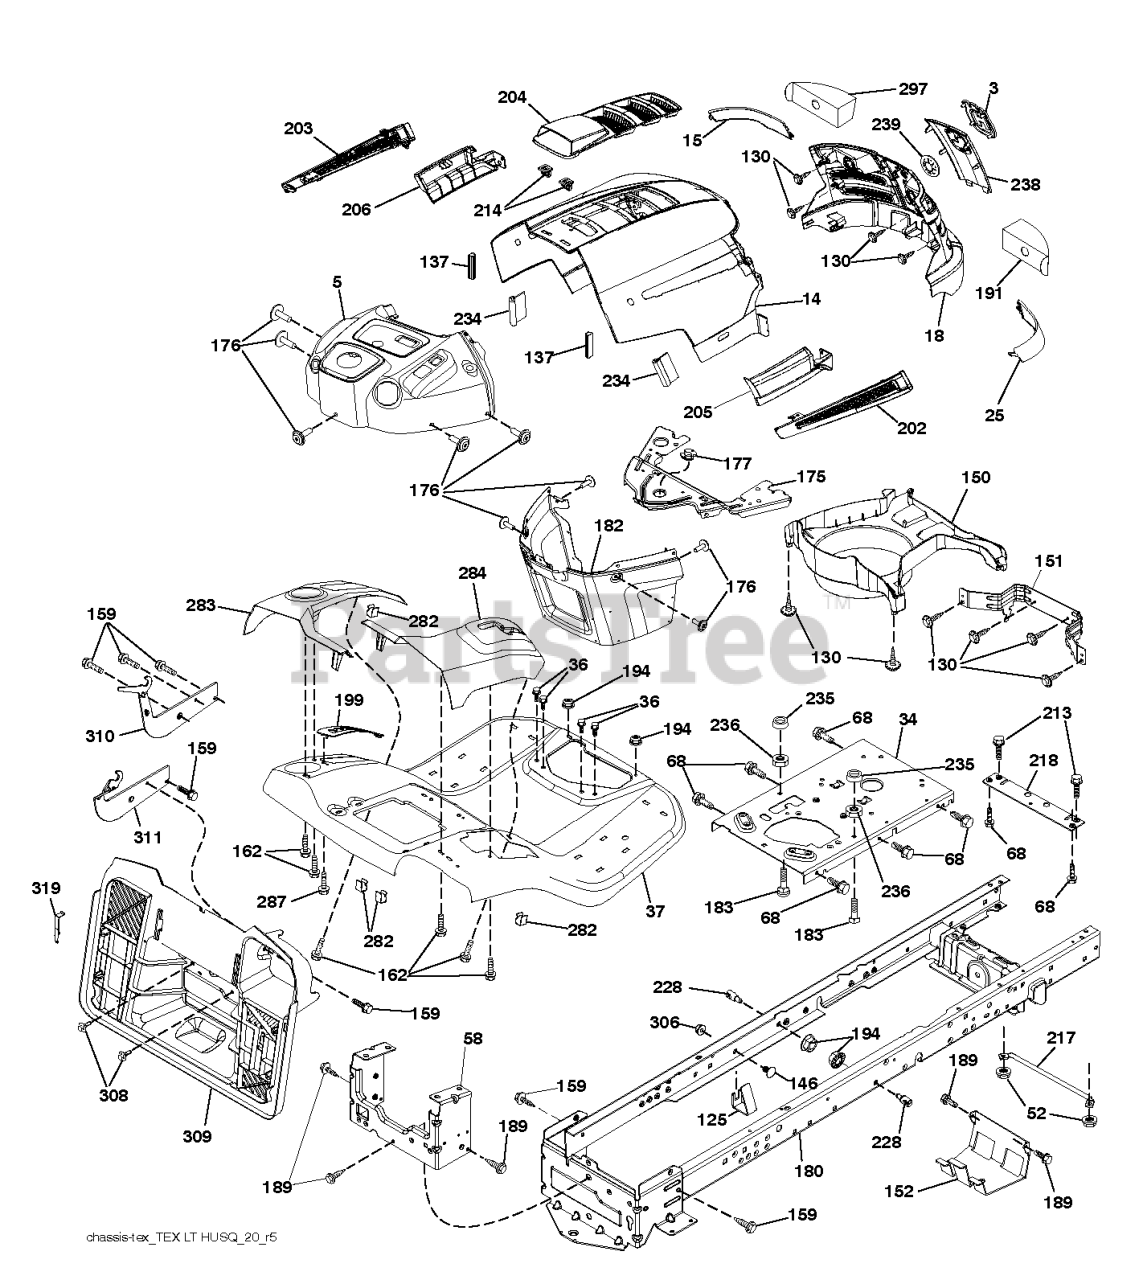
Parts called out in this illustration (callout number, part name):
3	RP LOGO
5	SUBASM.DASH.UPPER.HLT.498
14	HOOD.HUSQVARNA.LT.ORANGE
15	LENS.HUSQVARNA LT.RH
18	GRILLE.SVC.HUSQVARNA.GREY
25	LENS.HUSQVARNA LT.RH
34	PLATE PLATE ENGINE
36	SCREW 5/16"
37	FENDER.TEX.SRD.CRD.BASE
52	LOCKNUT
58	DRAWBAR UPPER 2PC SMALL FENDER
68	Screw 5/16-18 x 1/2 Hex, Self Tapping 5/16-18 x 1/2
125	CLIP.FUEL.LINE
130	SCREW.#10 X 0.750.BOS
137	BUMPER DASH
146	BOLT.RDHD.SHT.SQNK.3/8-16X5/8
151	BRACKET PIVOT
152	SHIELD.BROWNING.W/TEX
159	SCREW, 3/8-16X3/4
162	SCREW.HI-LO.CONSOLE
175	CROSSMEMBER
176	SCREW.#10-24X5/8.RN.QU
177	BUSHING STEERING
180	CHASSIS.WLDMNT.14GA.2PC.18".TI
182	DASH.LOWER.PREDATOR LT
183	BOLT.5/16-18X1-1/4 FULL THD
189	SCREW
191	INSERT.REFLECTIVE.RH.
194	NUT LOCK HEX FLANGE 5/16-18
199	PLATE DECK LIFT
202	VENT.SIDE.HUSQVARNA.LT.RT
203	VENT.SIDE.HUSQVARNA.LT.LFT
204	SUBASM.TOP.VENT.HUSQ.LT
205	SKIRT.SIDE.HUSQVARNA.LT.RT
206	SKIRT.SIDE.HUSQVARNA.LT.LEFT
213	BOLT
214	CLIP.RETAINER.TINNER.
217	ROD.PIVOT.HOOD
218	X-PIECE.HOOD.STOP.NON/
228	STUD.FASTNER.W/ANTI-ROTATE
234	BUMPER.HOOD.TEX.HUSQVARNA
235	SPACER FENDER
236	NUT.CENTERLOCK.5/16-
238	TRIM.HUSQ LT.668
282	CLIP.RETAINER.CONSOLE.LT.HUSQ
283	CONSL.DECKLIFT.LH.SRD.TEX.CRD
284	CONSL.SHFT.PEDAL.RH.SRD.TEXCRD
287	SCREW 1/4X20
297	INSERT REFLECTIVE
306	NUT LOCK FLG 3/8-16 UNC
308	BOLT.5/16-18UNCX3/4 W/SEMS.BLK
309	BACKPLATE.BAGGER.V2.SRD
310	LH.ADJUST.HANGER.BRACKET.ASM
311	RH.ADJUST.HANGER.BRACKET.ASM
319	BRACKET.ACTUATOR.BAGGER.SRD
